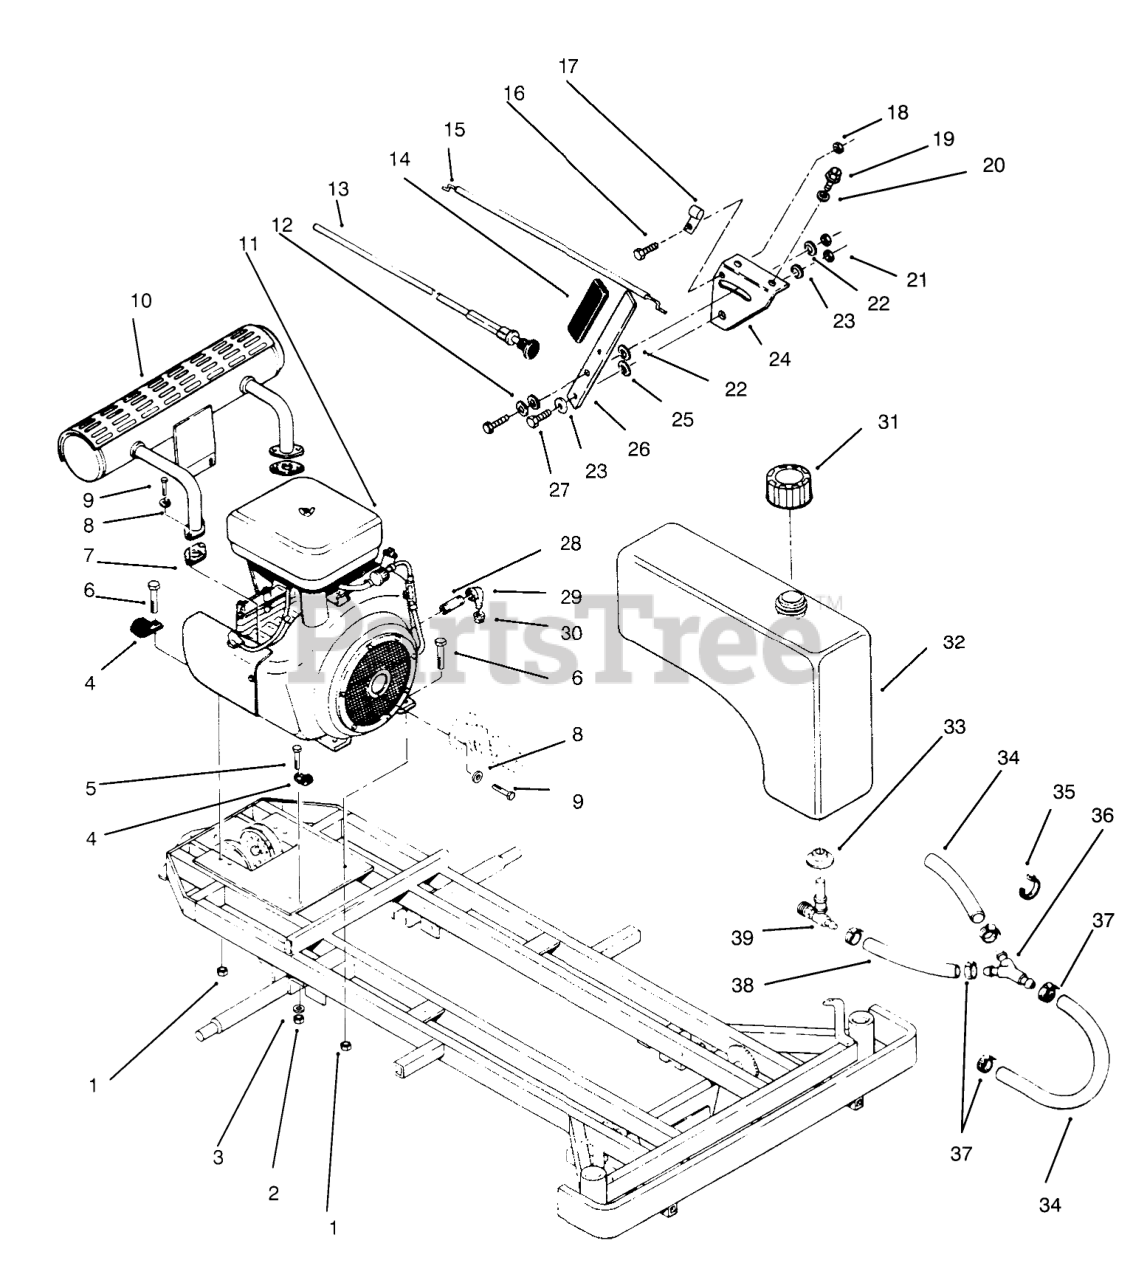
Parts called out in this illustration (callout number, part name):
1	NUT-LOCK, NI
2	NUT-LOCK, NI
3	WASHER-PLAIN
4	CLIP
5	SCREW-HH
6	SCREW-HHF
7	GASKET-EXHAUST
8	WASHER-LOCK
9	SCREW-HSH
10	MUFFLER
11	Engine-24 HP Toro Power Plus P224 G I/10966 Spec. E Engine
12	WASHER-SPRING DISC
13	CABLE-CHOKE
14	GRIP BRAKE20258-K
15	CABLE-CHOKE CONTROL
17	CLIP BOWDEN WIRE
18	NUT-LOCK, NI
19	SCREW-HH
20	WASHER-LOCK
22	FRICTION WASHER
23	WASHER-FLAT
24	CABLE/BRKT ASM
25	SPACER CLUTCH ARM
26	Handle
27	SCREW-HH
28	NIPPLE-PIPE
29	ELBOW-STREET, 90 DEG
30	CAP-PIPE
31	GAS CAP ASM
32	Tank-Fuel (Incl. Items #33 & 39)
33	BUSHING
34	HOSE-GAS
35	TIE-CABLE
36	FITTING-FUEL 45-Y
37	CLAMP-HOSE
38	HOSE-FUEL
39	VALVE-FUEL
